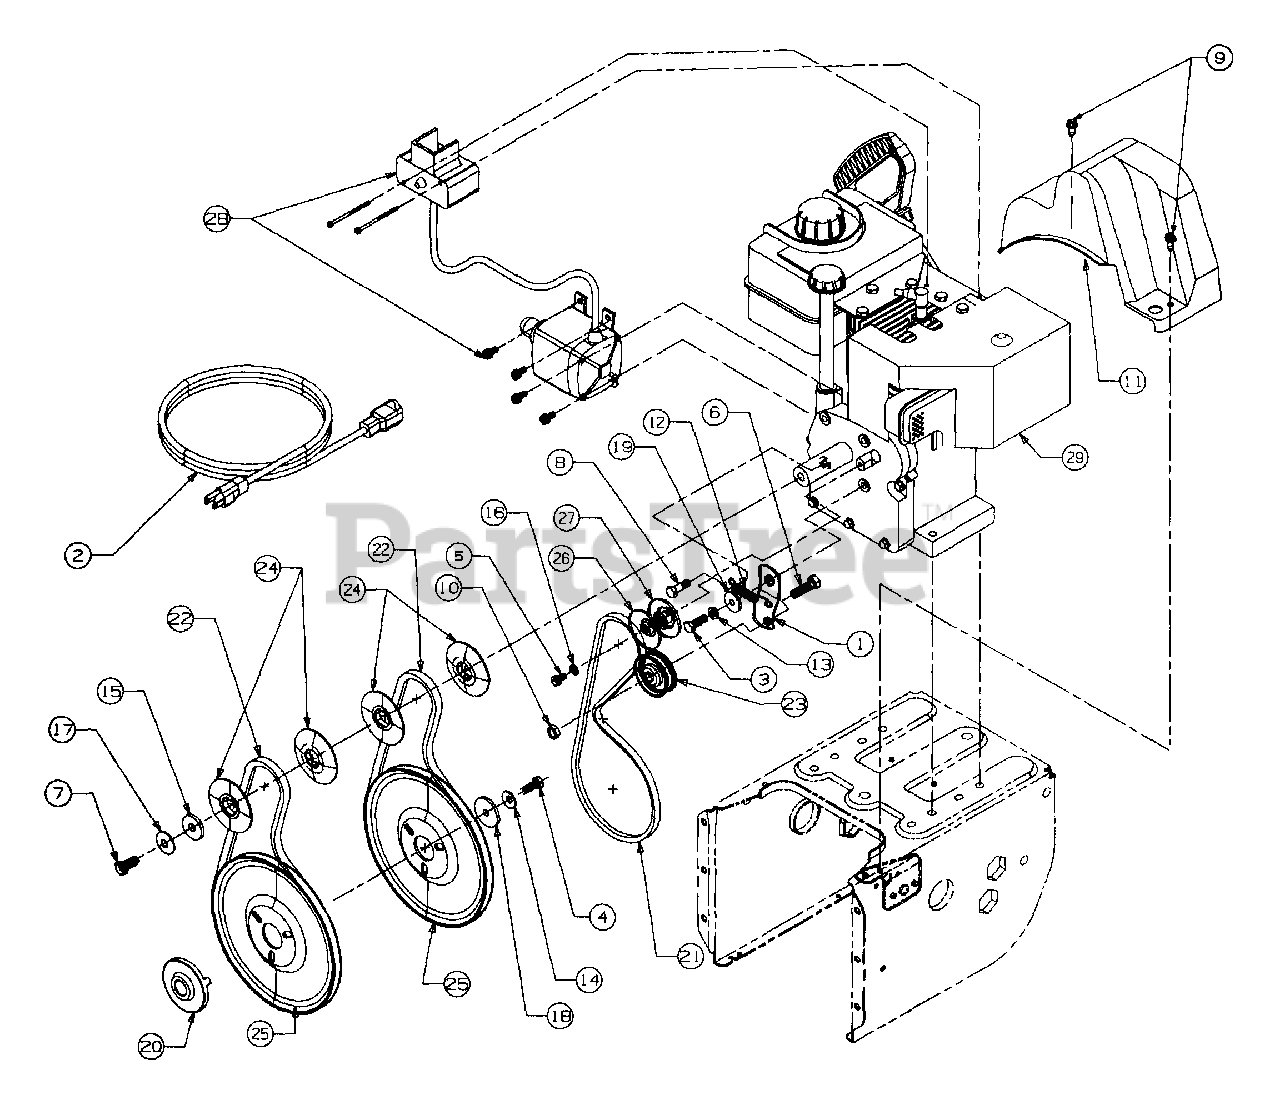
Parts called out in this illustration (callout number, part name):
3	Screw-Hex
4	Screw-Hex
5	Screw-Hex
6	Screw-Hex
7	Screw-Hex
8	Screw-Hex
9	Screw-Hex
10	Nut-Hex
11	Cover-Belt
12	Spring
13	Washer-Lock
14	Washer-Bell
15	Washer-Flat
16	Washer-Lock
17	Washer-Bell
18	Washer-Flat
19	Spacer
20	Adapter-Pulley
21	V-Belt
22	V-Belt
23	Idler-Flat
24	Pulley Half
25	Pulley-Auger
26	Pulley Half
27	Pulley Half
28	Electric Start Kit
